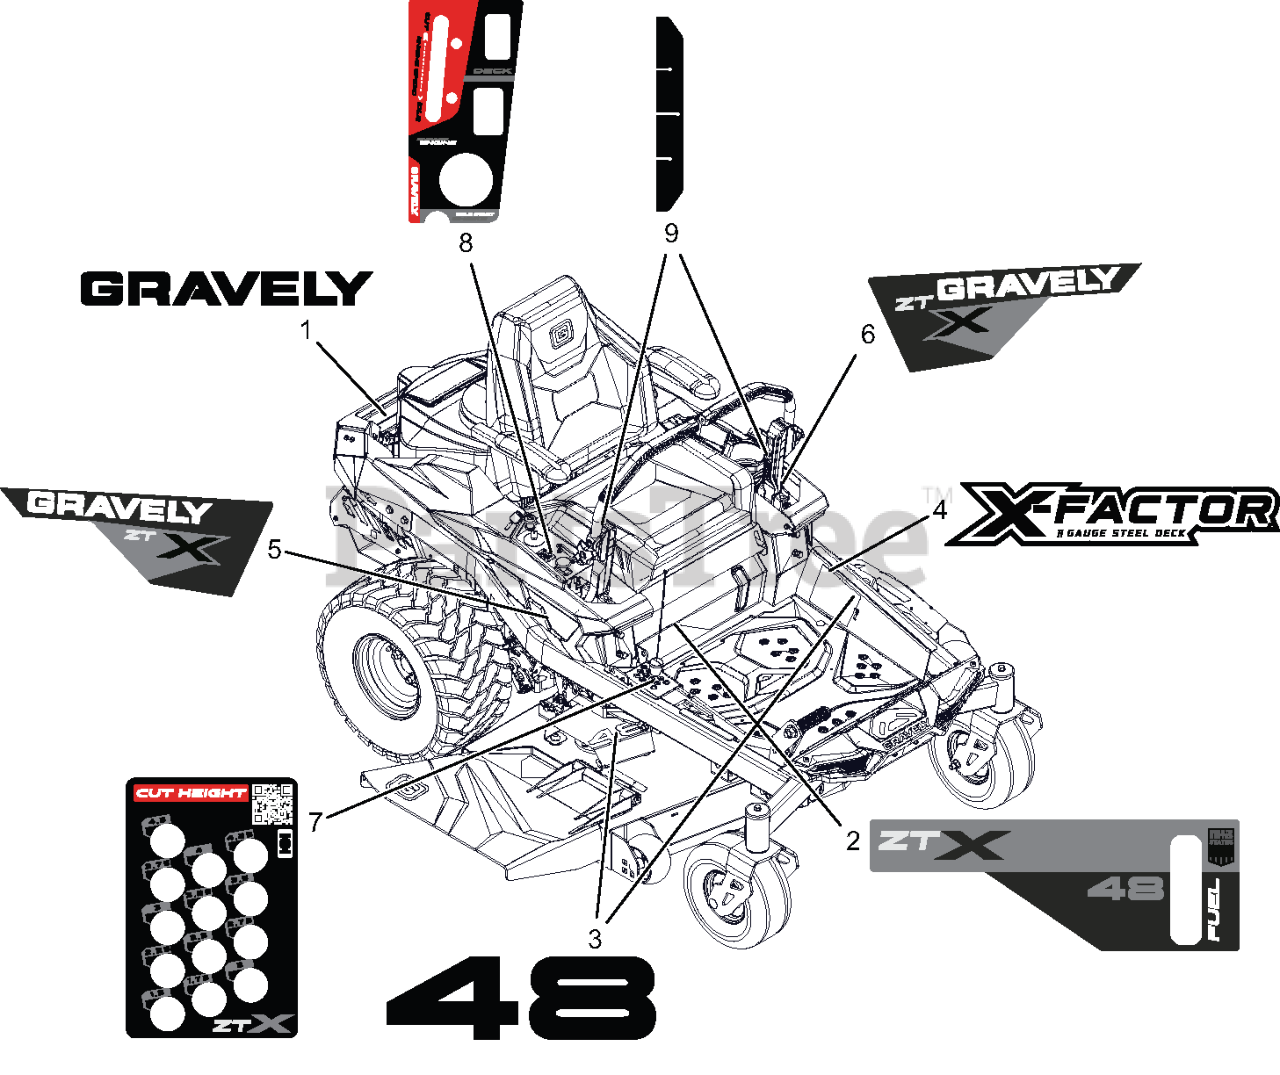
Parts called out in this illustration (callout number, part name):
1	DECAL- GRAVELY
2	DECAL- ZTXL 48-KICK PLATE
3	DECAL- DECK 48"
4	DECAL- DECK X-FACTOR
5	DECAL- ZT X FENDER RH
6	DECAL- ZT X FENDER LH
7	DECAL- HEIGHT OF CUT-X
8	DECAL- CONTROL PANEL-GRAVELY
9	DECAL- HIRTH INDICATOR
